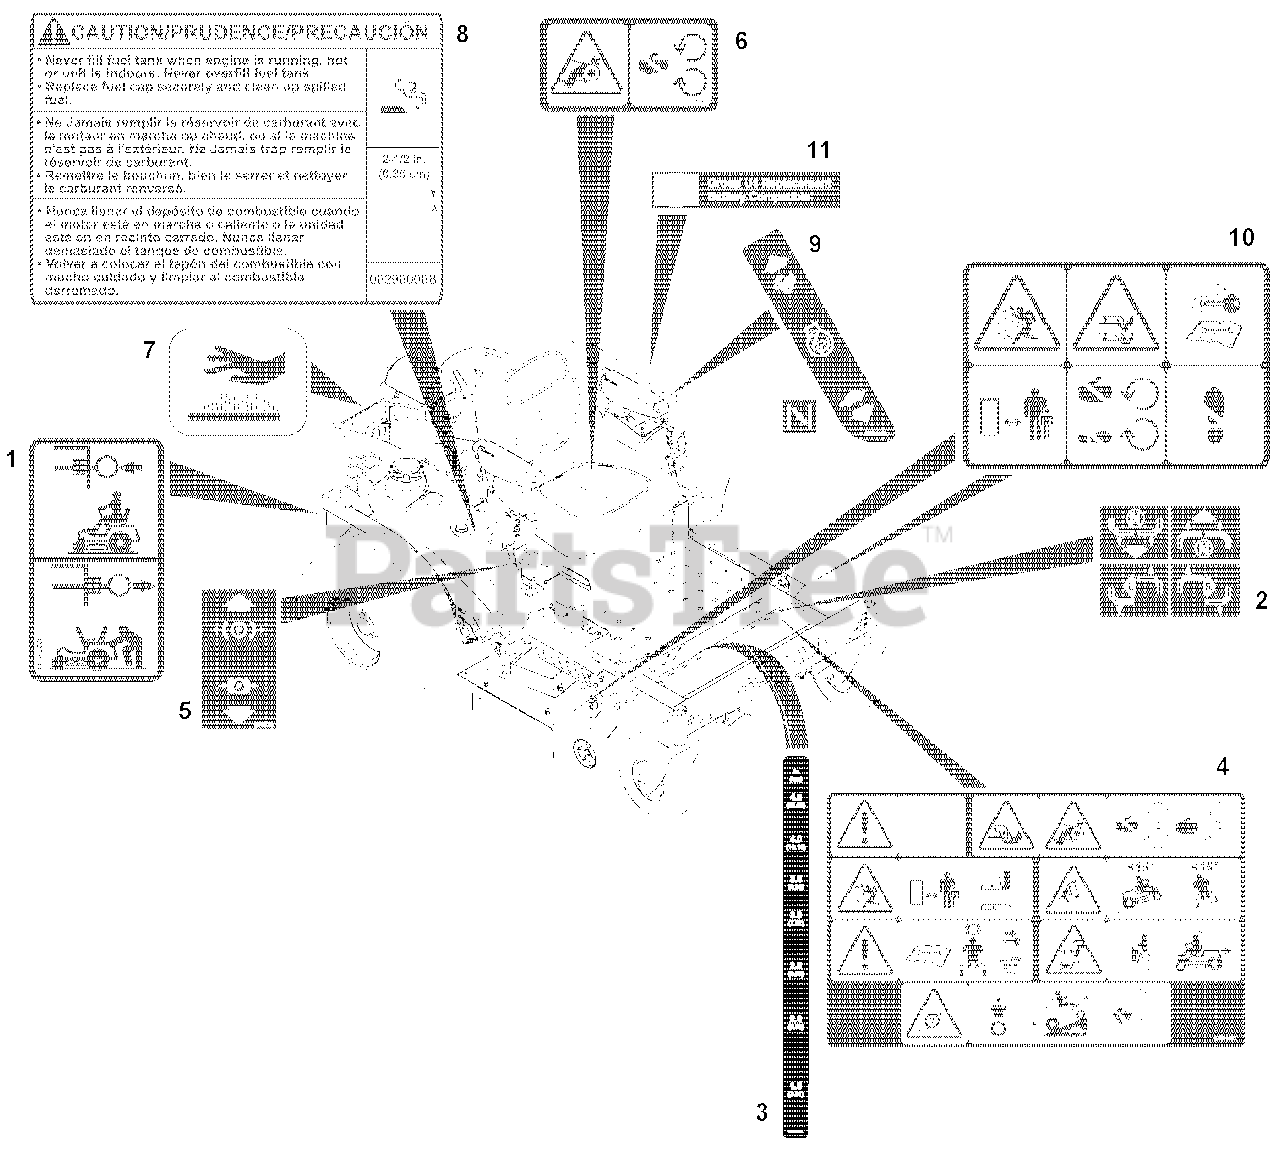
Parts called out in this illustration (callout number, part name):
1	Decal, Transmission Disconnect
2	Decal, Instructional Steering
3	Decal, Cut Height
4	Decal, Safety, Main
5	Decal, Parking Brake Lever
6	Decal, Safety, Guarding
7	Decal, Hot Surface
8	Decal, Fuel Warning
9	Decal, Control
10	Decal, Mower Deck Safety
11	Decal, Battery Replacement
